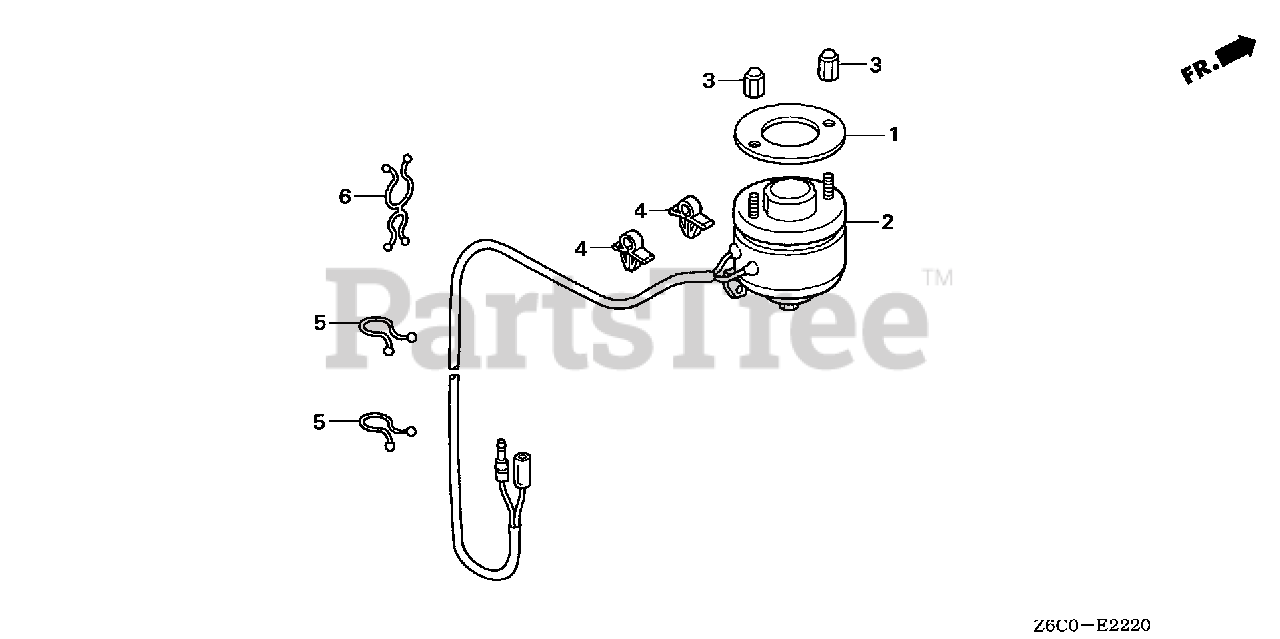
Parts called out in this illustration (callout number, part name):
1	PLATE, SOLENOID
2	SOLENOID ASSY., ROTARY
3	NUT, SPECIAL CAP
4	CLIP, WIRE HARNESS (6MM) (WHITE)
5	CLIP, PURSE LOCK (8MM)
6	CLIP, PURSE LOCK
